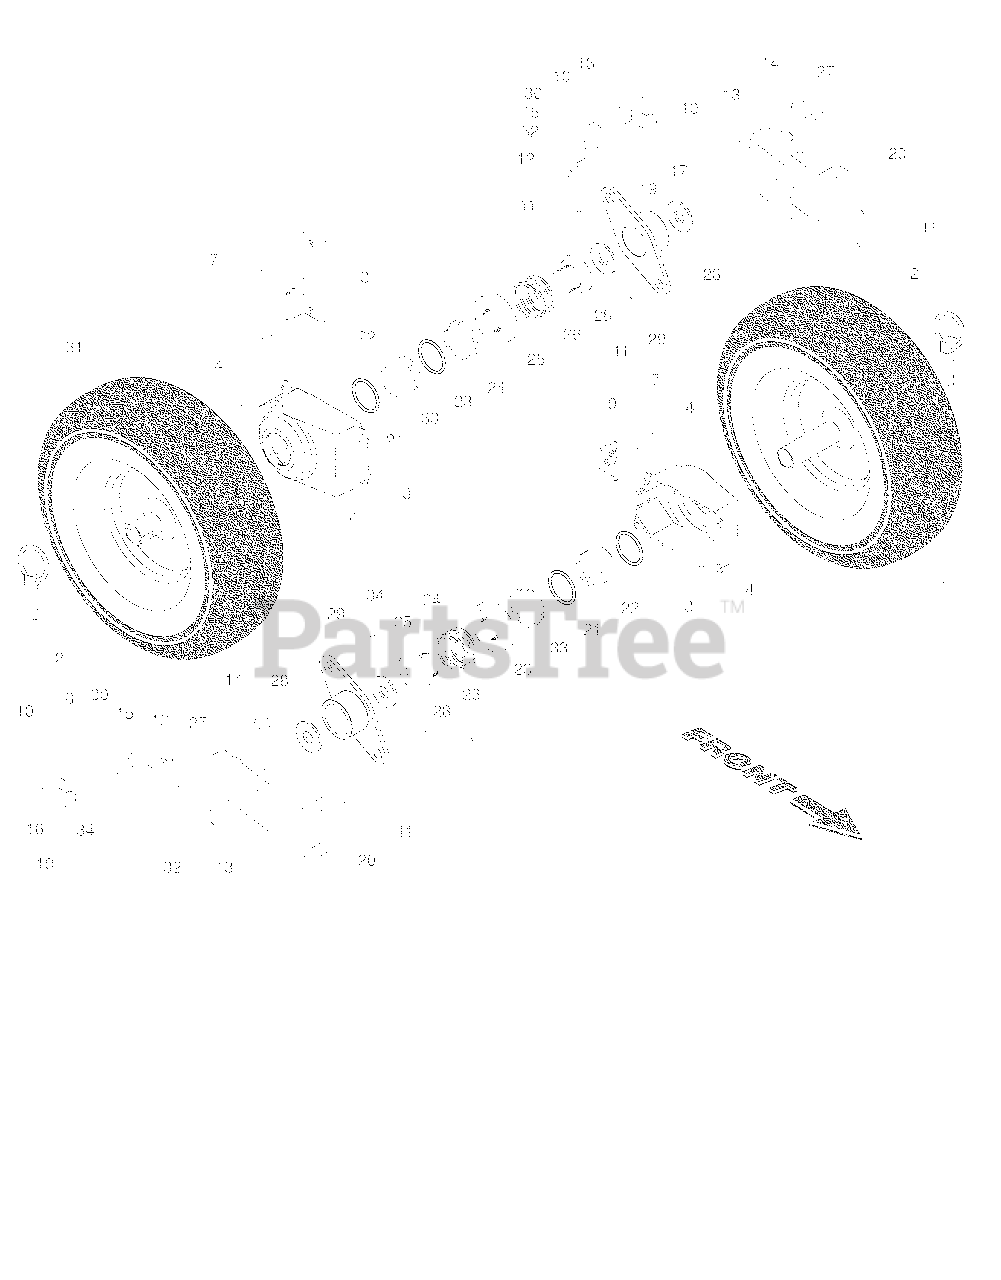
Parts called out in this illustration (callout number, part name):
1	Wheel Assembly, 16", Power Steering, LH
2	Pin, Klik 1/4
3	Cover, Power Steering
4	Bolt, Shoulder #10-24 x 5/8
7	Capscrew, Hex Head, Flanged 3/8-16 x 1
8	Bracket, Steering Cable, RH
9	Bracket, Steering Cable, LH
10	Screw, Hex Head 1/4-20 x 3/8
11	Screw, Hex Head 5/16-18 x 1/2
12	Link, Steering Lever
13	Yoke, Steering
14	Pin, Steering Lever
15	Bellcrank
16	Bracket Assembly, LH Steering
17	Bracket Assembly, RH Steering
18	Pin, Steering Bellcrank
19	Retainer, Hairpin
20	Bracket, Steering
21	Driver, Wheel
22	Ring, Wire Retainer
23	Lobe, Wheel
24	Slide, Clutch
25	Spring, Clutch Slide
26	Lobe, Axle
27	Key, Square
28	Washer, Thrust (1")
29	Bearing, Axle
30	Spring, Return
31	Wheel Assembly, 16", Power Steering, RH
32	Clip, Retainer
33	Ring, Retaining
34	Screw, Hex Head 5/16-18 x 5/8
